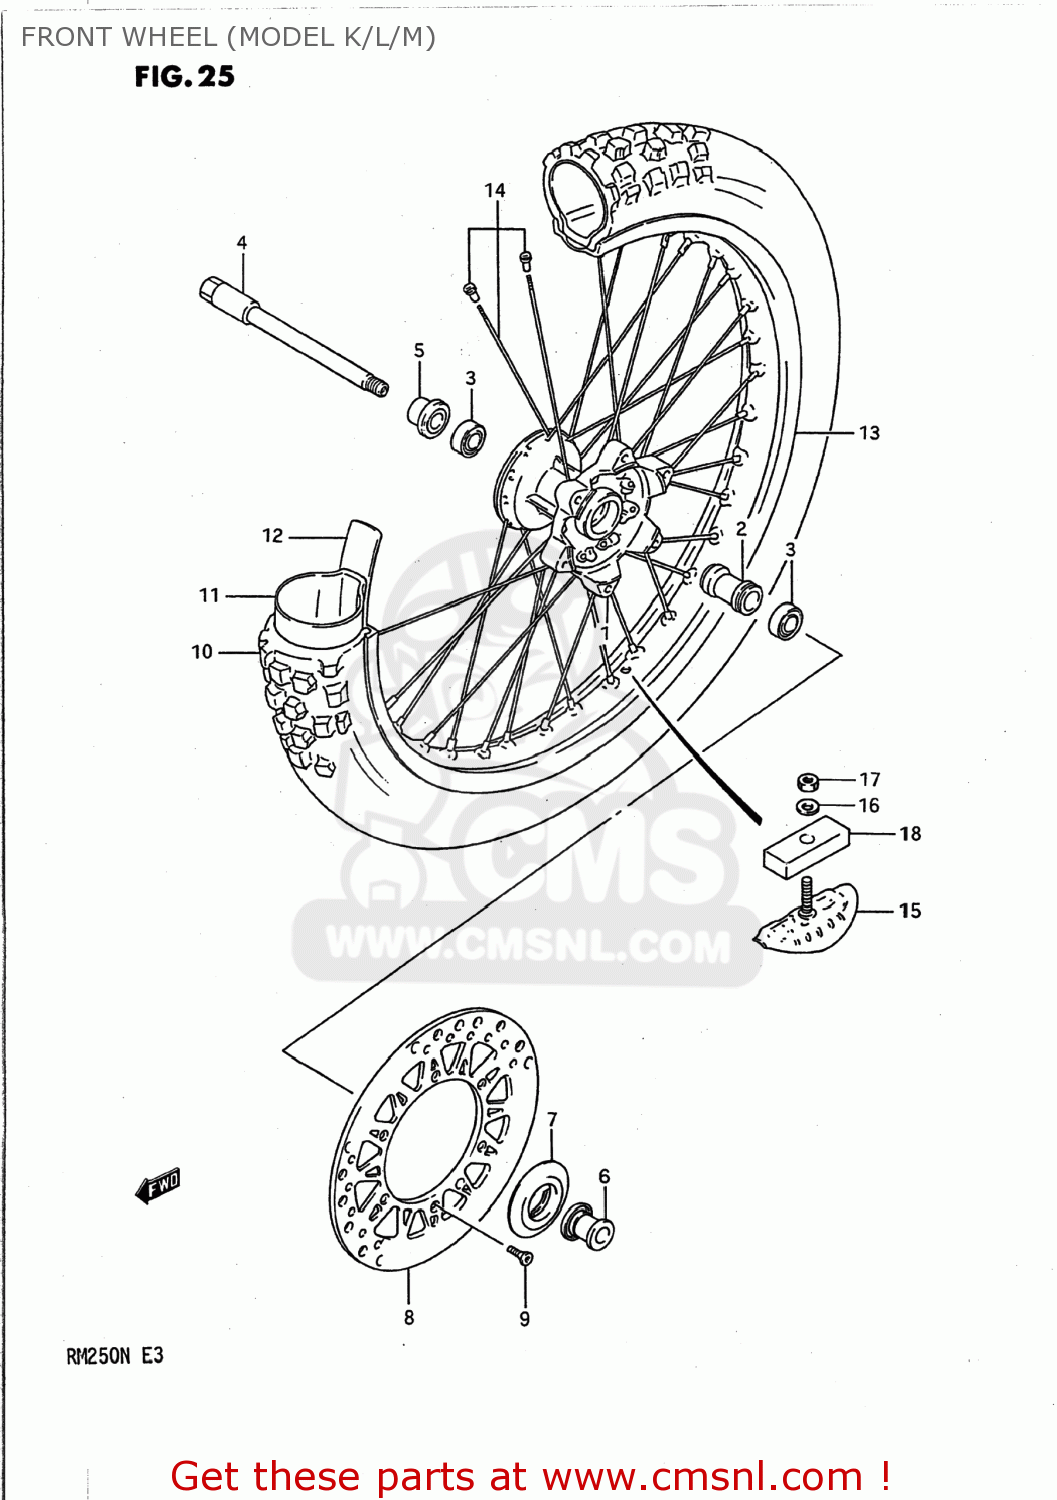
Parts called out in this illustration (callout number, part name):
1	HUB,FRONT
2	SPACER,FR HUB BEARING
3	BEARING
4	AXLE,FRONT
5	SPACER,FR AXLE,R
6	SPACER,FRONT AXLE,LEFT
7	CAP,FR HUB,L
8	DISC,BRAKE
9	SCREW
10	TIRE,FRONT
11	TUBE
12	PROTECTOR,WHEEL,INNER
13	RIM,FRONT WHEEL (1.60X2
14	SPOKE SET,FRONT
15	STOPPER,BEAD
16	WASHER
17	NUT
18	CUSHION,BEAD STOPPER
